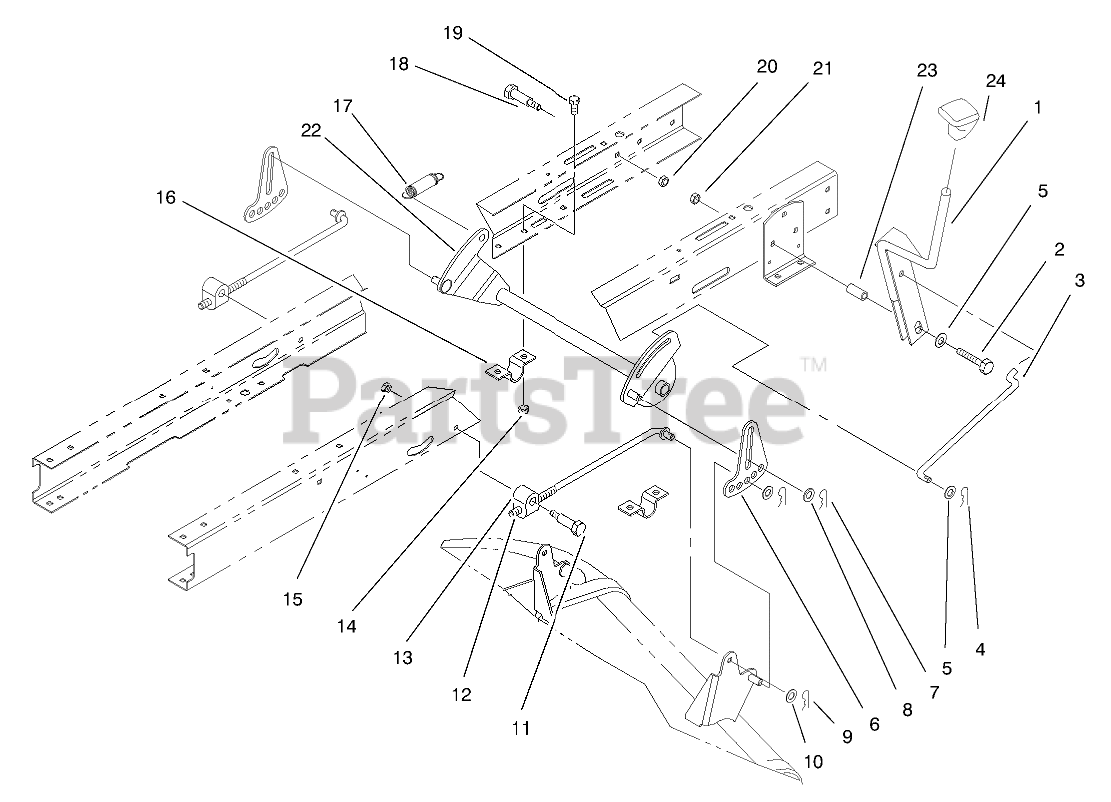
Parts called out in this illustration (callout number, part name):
1	HOC LEVER ASM
2	SCREW-HH
3	LINK-HOC
4	PIN-COTTER
5	WASHER-FLAT
6	LINK-ADJUSTING, HOC
7	PIN-COTTER
8	WASHER-HARDENED
9	PIN-COTTER
10	WASHER-FLAT
11	SCREW-SHOULDER, HH
12	ROD-HANGER, REAR
13	TRUNNION-HOC
14	NUT-LOCK, NI
15	NUT-LOCK, NI
16	CLAMP-PIVOT, HOC
17	SPRING-EXTENSION
18	SCREW-SHOULDER, HH
19	SCREW-HH
20	NUT-LOCK, NI
21	NUT-LOCK, NI
22	PIVOT ASM
23	SPACER
24	KNOB-SHIFT
